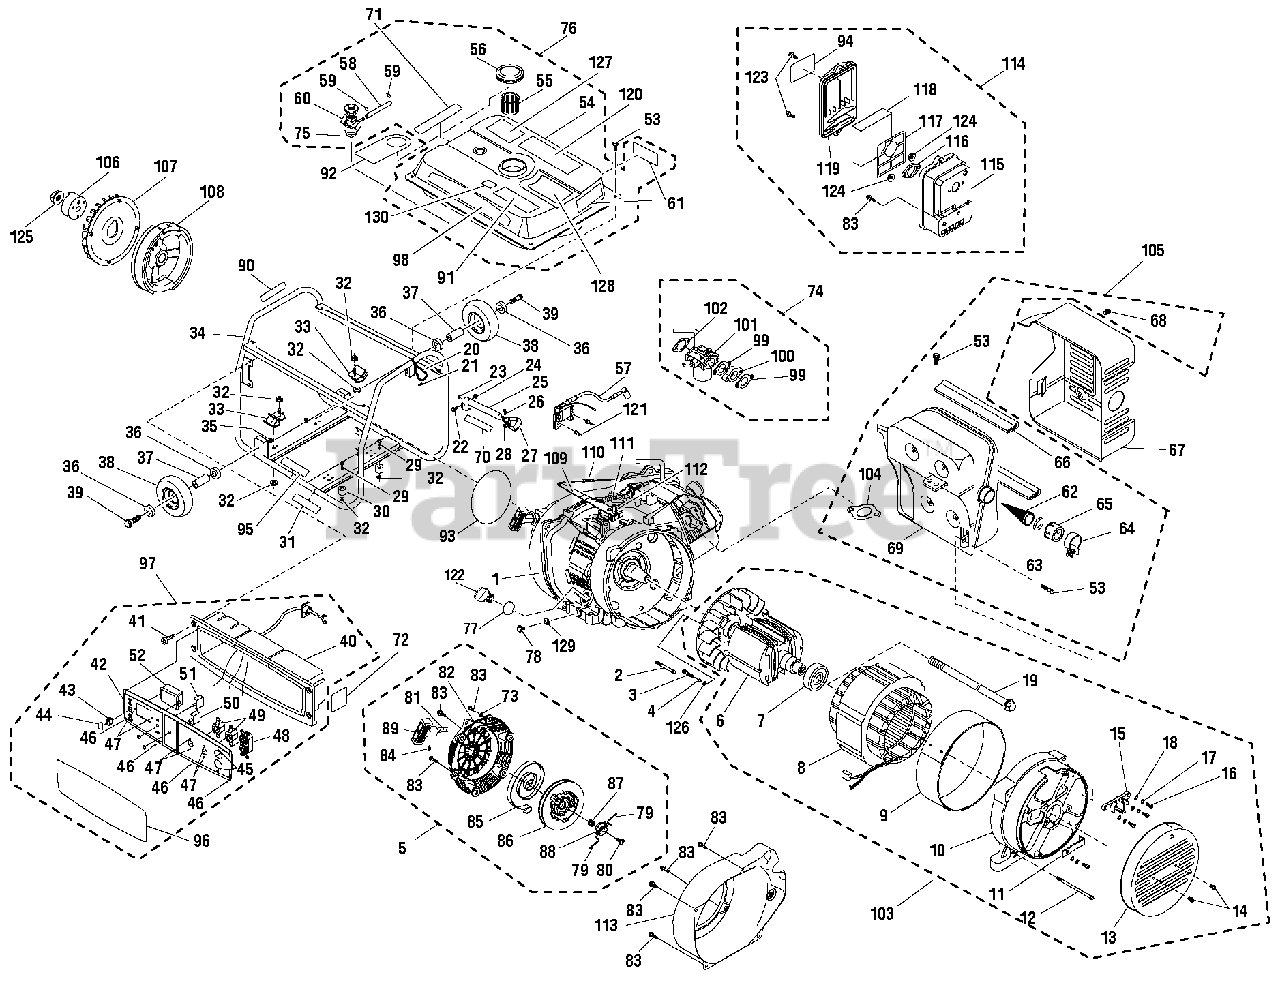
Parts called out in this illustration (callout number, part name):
1	Engine SPE195
2	Bolt (M8 x 35 mm)
3	Bolt (M6 x 12 mm)
5	Recoil Stator Assembly
6	Rotor Assembly
8	Stator Assembly
9	Stator Cover
10	Rear Frame
11	Wire Compressing Plate
12	Bolt (M6 x 103 mm) (88)
13	Rear End Cover
14	Bolt (M6 x 10 mm)
15	Wire Rack
16	Screw (M5 x 14 mm)
17	Lock Washer (M5)
18	Washer (M5)
22	Bolt (M8 x 40 mm)
23	Handle Stem Head
24	Lock Nut (M8)
26	Square Bolt
29	Screw (M8 x 40 mm)
30	Alternator Vibration Absorber
31	Combustion Warning Label
33	Engine Vibration Absorber
35	Lock Nut (M10 x 1.25 in.)
36	Wheel Bushing
37	Axis Cover
39	Bolt (M10 x 75 mm)
40	Control Box
41	Screw (M6 x 14 mm)
42	Control Panel
43	Engine Switch
44	Switch Jacket
45	Bolt (M3.5 x 9 mm)
46	Bolt (M3.9 x 9 mm)
47	Bolt (M4 x 8 mm)
48	120 V 20 Amp Receptacle
49	120 V 30 Amp Receptacle
50	AC Circuit Breaker (20 A)
51	AC Circuit Breaker (25 A)
52	4 in 1 Digital Meter
53	Bolt (M6 x 12 mm)
54	Fuel Tank
55	Fuel Strainer
56	Fuel Tank Cap
57	Ignition Module
58	Fuel Hose
59	Fuel Hose Clip
60	Fuel Cock
61	Hot Surface Label
62	Muffler Screen
65	Muffler Screen Cover
66	Shockproof Bar
67	Muffler Cover
68	Bolt (M6 x 10 mm)
70	Locking Pin Label
71	Start Guide Label
72	Ground Label
73	Bushing Block
74	Carburetor Assembly
76	Fuel Tank Assembly
77	Oil Filler Seal
78	Drain Plug (M10 x 1.25-16 )
82	Starter Case
83	Screw (M6 x 12 mm)
84	Rope Clip
85	Starter Spring
86	Drum Sheave
88	Pawl Guide
89	Starter Handle
90	Fire Danger Label
91	Ground Warning Label
92	Oil Hangtag
93	Engine Shround Logo
94	Choke Label
95	Lubricant Label
96	Control Panel Label
97	Control Panel Assembly (Inc. Key Nos. 40-52 & 96)
98	Logo Label
101	Carburetor
103	Alternator Assembly
104	Exhaust Gasket
105	Muffler Assembly
106	Starting Hub
109	Governor Arm
111	Carburetor Spring
114	Air Cleaner Assembly
115	Air Filter Case
117	Element Fitting Plate
118	Air Filter Element
119	Air Filter Cover
120	Warning Label
121	Screw (M6 x 20 mm)
122	Oil Cap/Dipstick
123	Screw (M6 x 12 mm, Fillister Hd.)
125	Nut (M16, Flange Hd.)
127	CPSC Label (English)
128	CPSC Label (Fr/Sp)
129	Drain Plug Gasket
130	E85 Label
